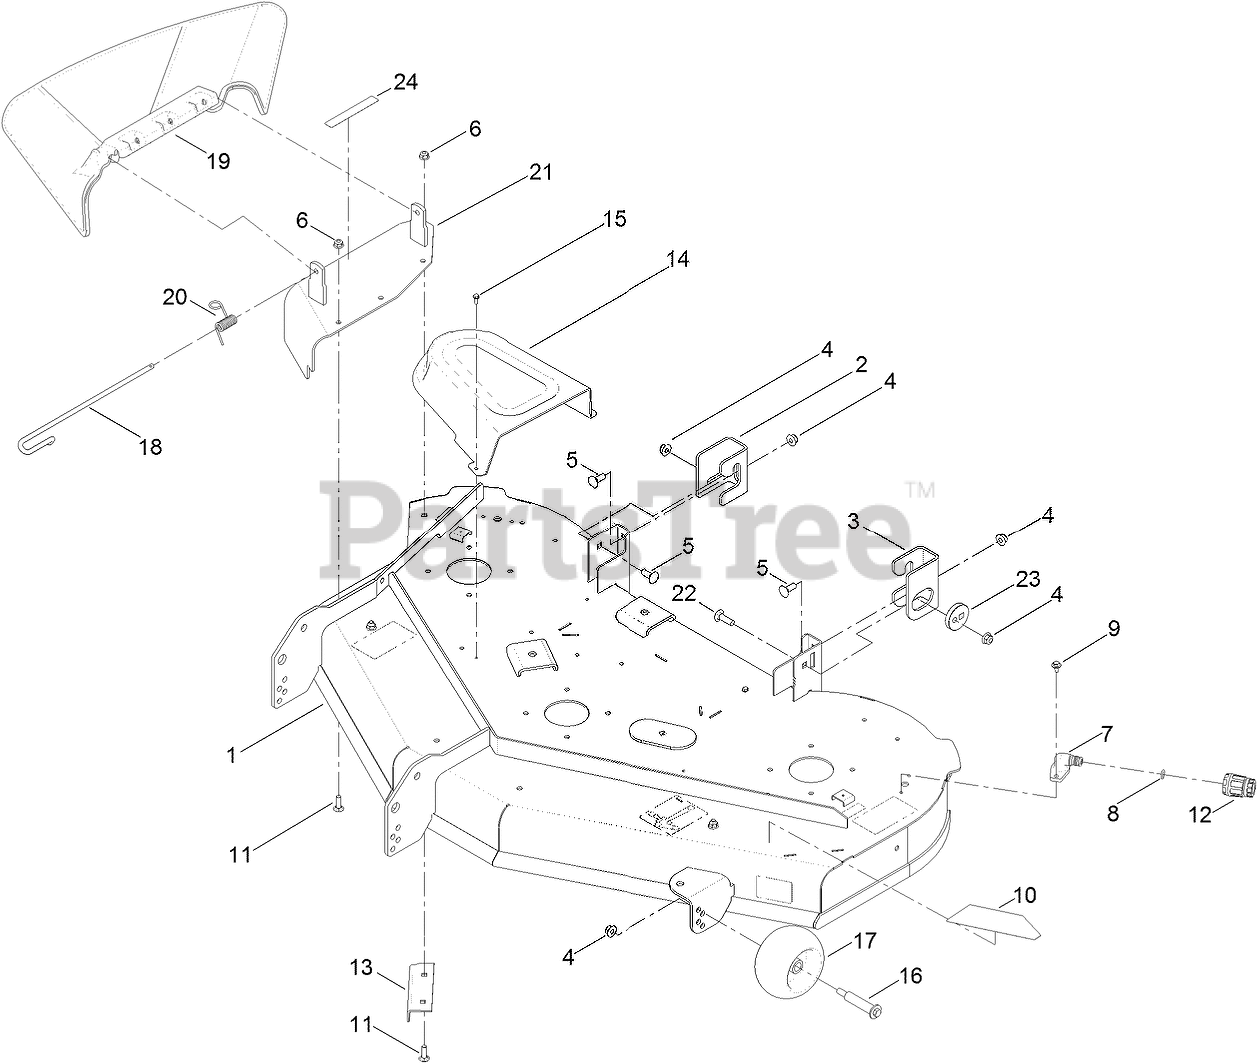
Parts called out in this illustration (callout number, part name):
1	50 INCH DECK AND DECAL ASM
2	BRACKET-HANGER, RH
3	BRACKET-HANGER, LH
4	NUT-HF, NI
5	BOLT-CARR
6	NUT-HF, NI
7	FITTING-WASHOUT
8	O-RING
9	SCREW-HHFTF
10	DECAL-DECK
11	SCREW-CARR
12	CONNECTOR-HOSE
13	BAFFLE-CUTOFF
14	COVER-BELT
15	SCREW-TAPTITE
16	BOLT-SHOULDER
17	ROLLER-SCALP, ANTI
18	PIN-CHUTE
19	DEFLECTOR-DISCHARGE
20	SPRING-TORSION
21	COVER-DISCHARGE
22	SCREW-CARR
23	ECCENTRIC
24	DECAL-DANGER
